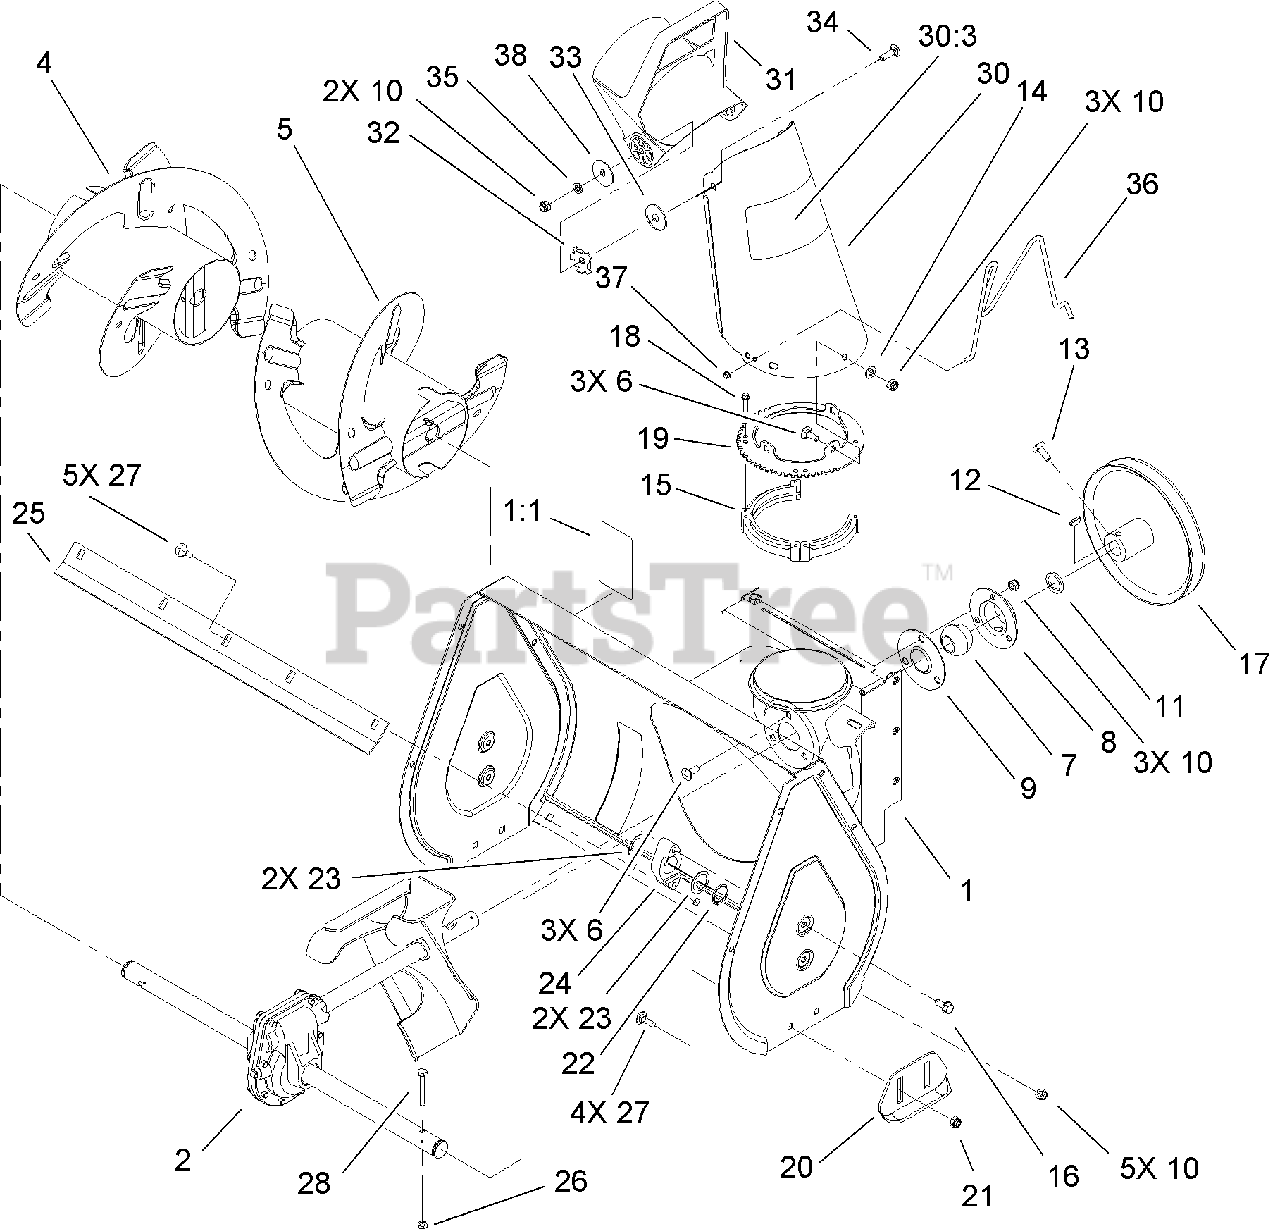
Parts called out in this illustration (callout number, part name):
1	24 INCH AUGER HOUSING ASM
1:1	DECAL-WARNING, AUGER (only on: 38078)
2	GEAR CASE ASM
4	24 INCH RH AUGER ASM
5	24 INCH LH AUGER ASM
6	SCREW-CARR
7	BEARING-BALL
8	FLANGE-CUP, BEARING
9	FLANGE-CUP, BEARING
10	NUT-LOCK, NI
12	KEY-WOODRUFF
13	SCREW-SET, SQH
14	WASHER-FLAT
15	RING-CHUTE, RETAINER
16	SCREW-HWHTF
17	PULLEY-IMPELLER
18	SCREW-SPECIAL
19	RING-CHUTE
22	RING-RETAINING
24	BEARING-AUGER
25	Scraper Blade
26	NUT-LOCK, NI
27	BOLT-CARR
28	SCREW-HH
30	Chute ASM
30:3	DECAL-DISCHARGE DANGER
31	CHUTE-DEFLECTOR
32	PLATE-FRICTION
33	WASHER-RUBBER
34	SCREW-CARR
35	WASHER-BELLEVILLE
36	WIRE-CHUTE
38	WASHER-FLAT
